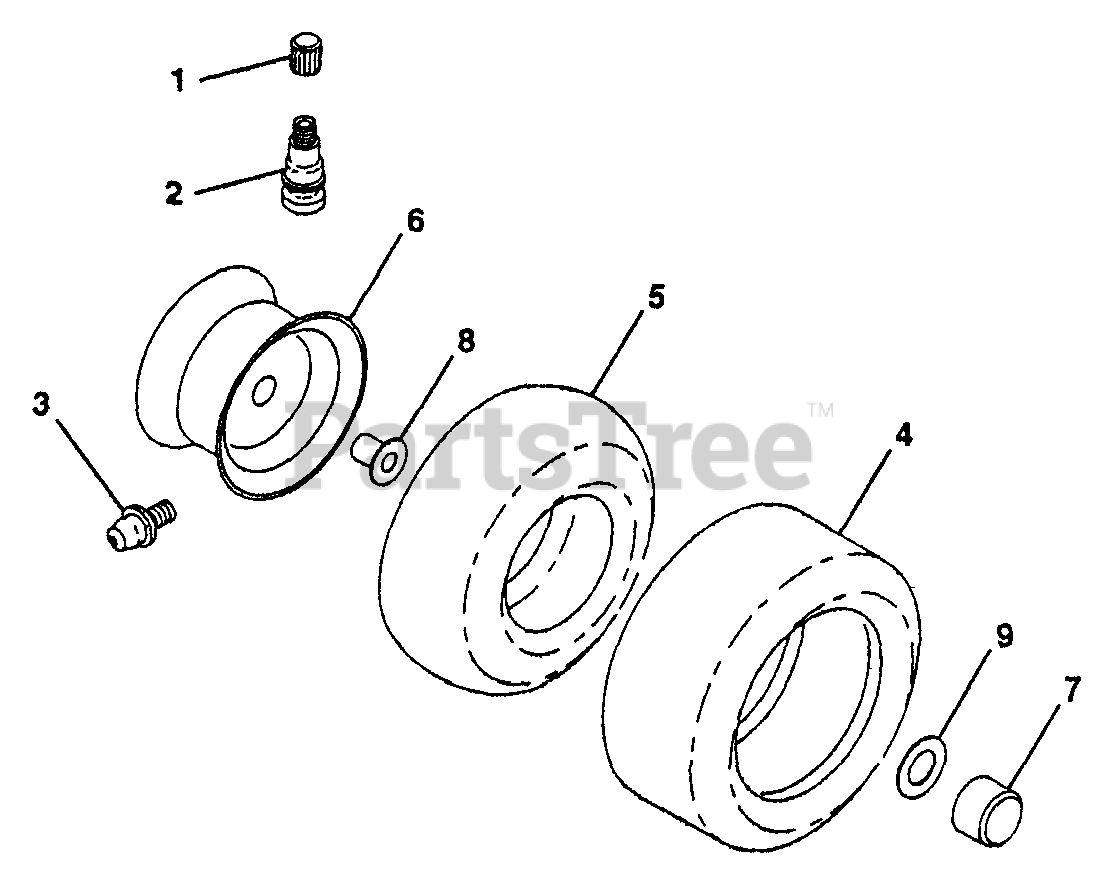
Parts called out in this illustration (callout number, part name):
1	Cap, Valve, Tire
2	Stem, Valve
3	Fitting, Grease
4	Tire, Front
4	Tire, Rear
5	Tube, Front Tire
5	Tube, Rear Tire
6	Rim Assembly, Front
6	Rim Assembly, Rear
8	Bearing, Flange
9	Washer 25/32 x 1-5/8 x 16 Gauge
